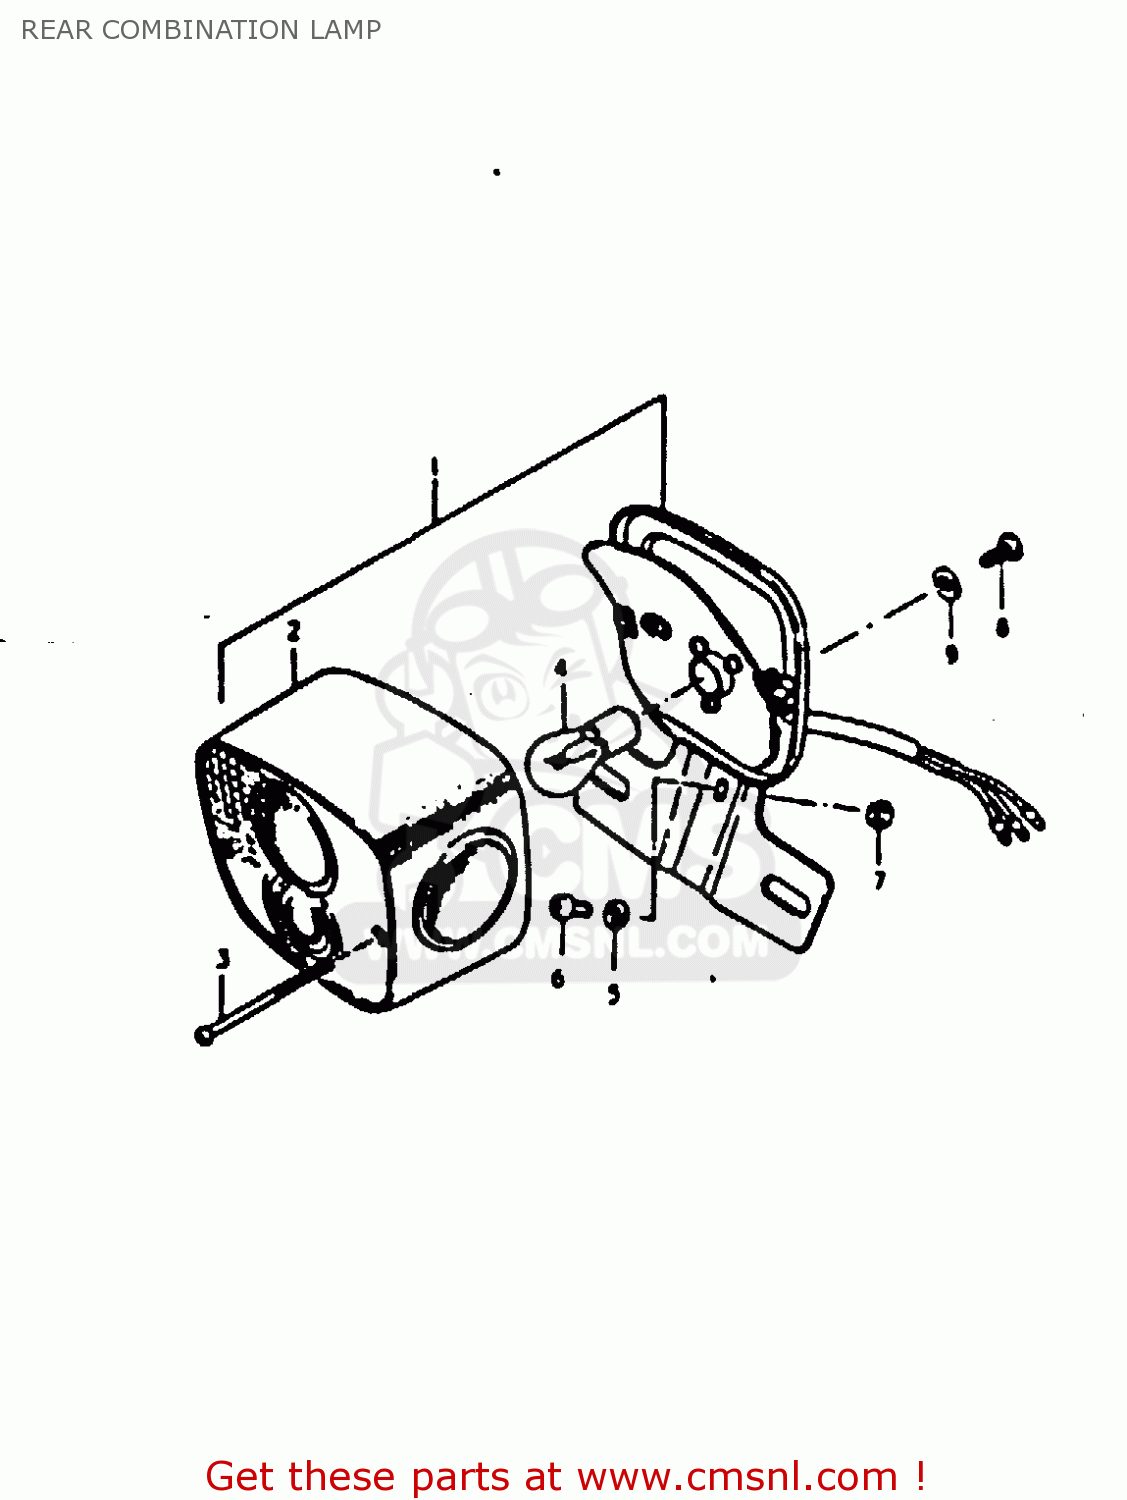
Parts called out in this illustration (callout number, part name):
1	LAMP ASSY, TAIL
2	LENS
3	SCREW (4X55)
4	BULB(6V10/3W,STANLEY,A4854H)
5	WASHER
6	SCREW
7	NUT
8	SCREW 6X12
9	WASHER
